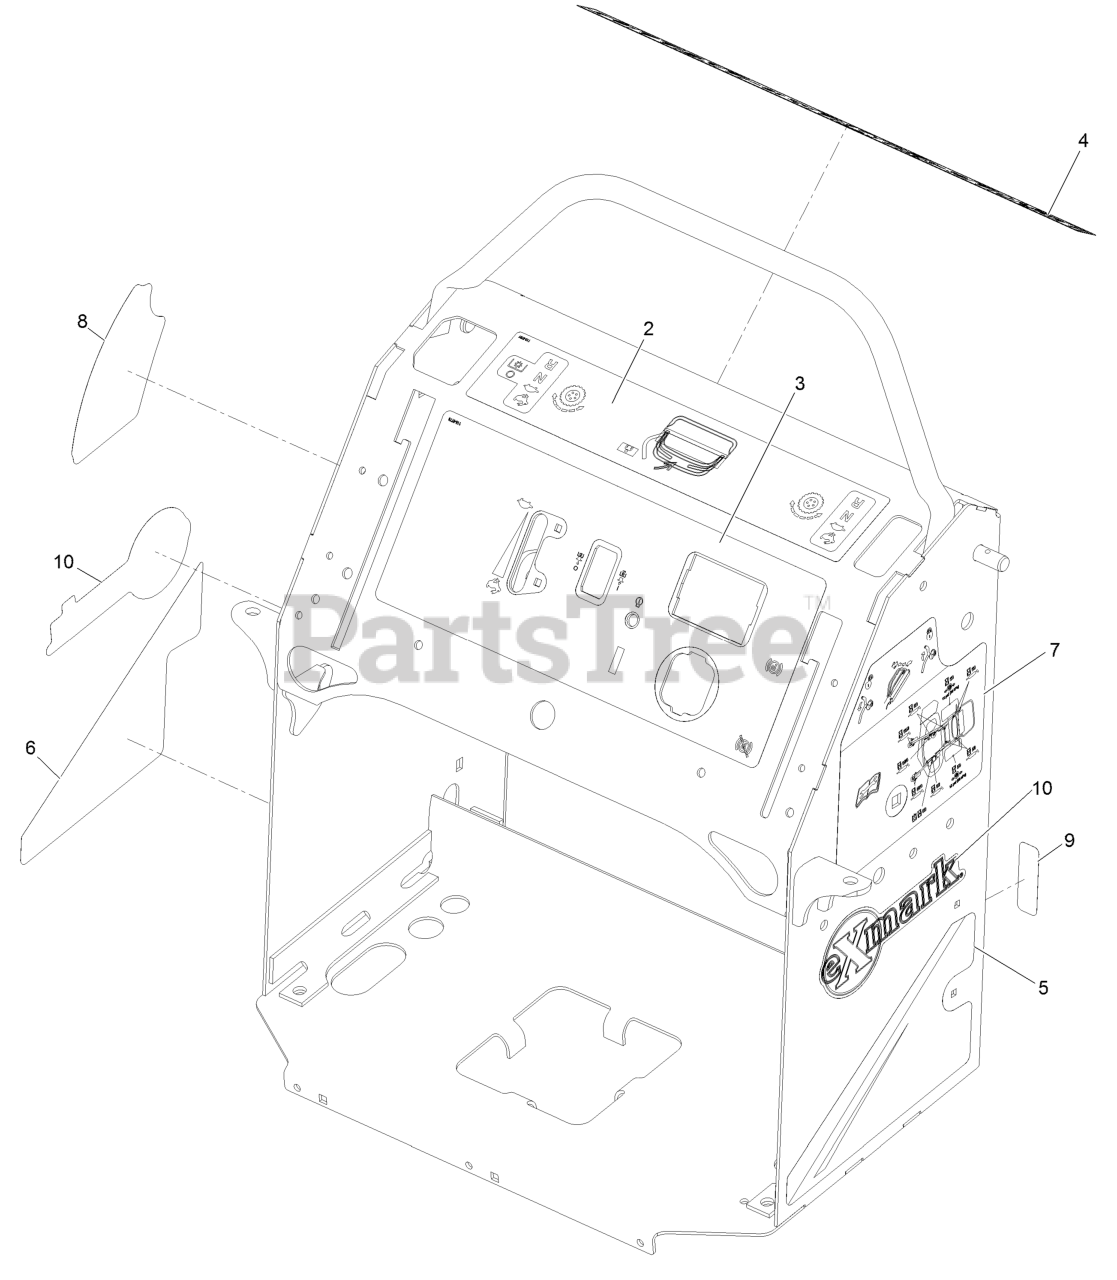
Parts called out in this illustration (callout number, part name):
2	DECAL-CONTROL PANEL EFI
3	DECAL-MOTION CONTROL
4	DECAL-WARNING
5	DECAL-LH PANEL
6	DECAL-RH PANEL
7	DECAL-SERVICE AID
8	DECAL-HEIGHT OF CUT
9	DECAL-FUSE
10	DECAL-EXMARK LOGO
